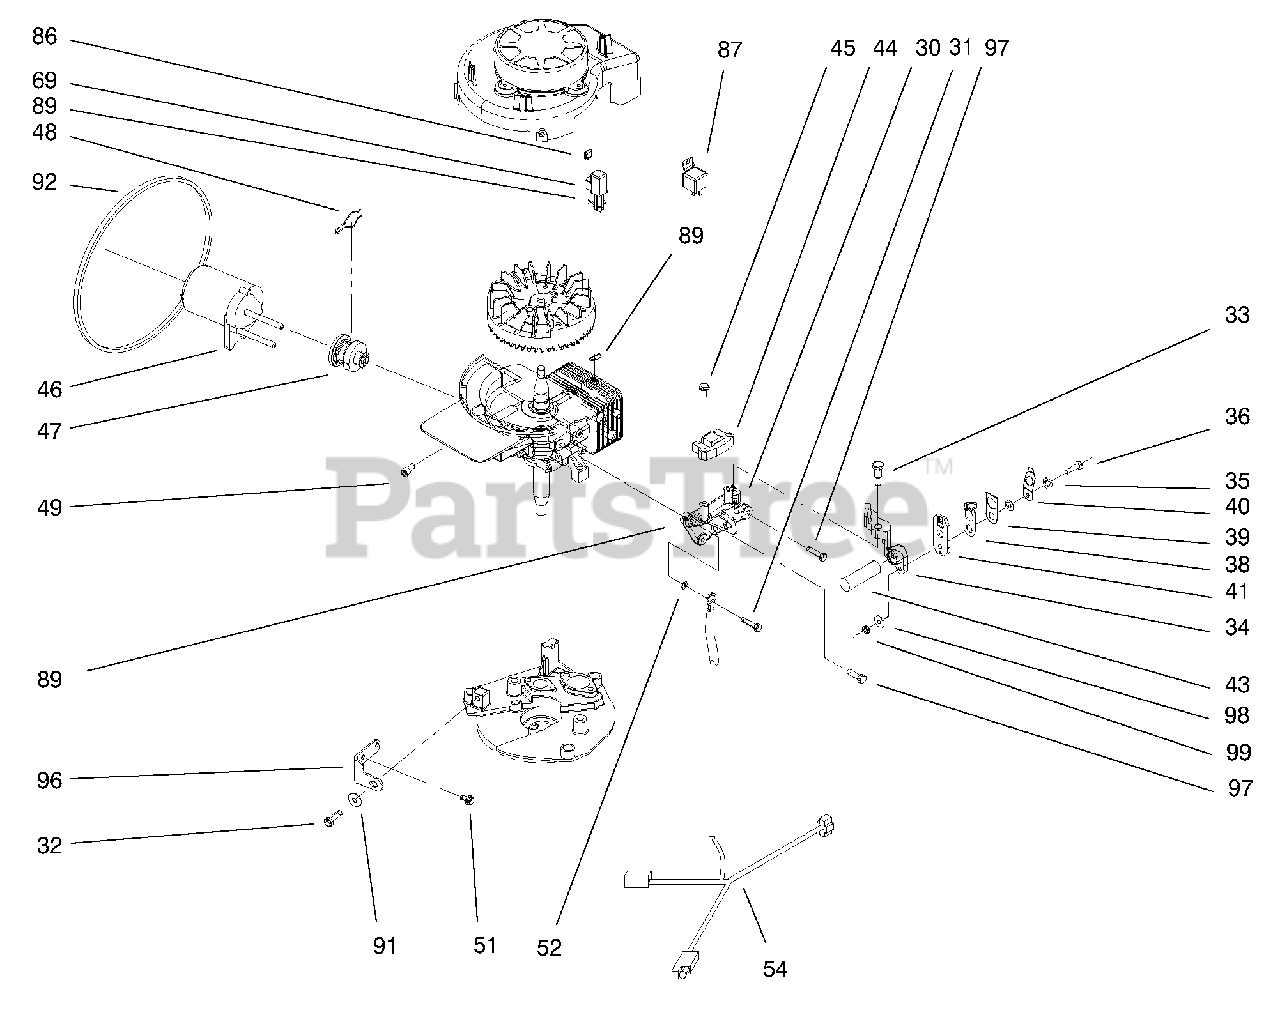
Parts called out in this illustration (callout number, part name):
30	Bracket-Alternator/ Brake
31	Screw-HH
32	Screw-HHF
34	Brake ASM
35	Washer
36	Screw-HH
38	Plate-Contact
40	Spring-Contact
41	Case ASM
42	Lead-Wire
43	Spring-Brake
44	Alternator ASM
46	Starter ASM
47	Pinion ASM
48	Spring-Drag
49	Screw-HSH
51	Screw-HH
52	Washer-Lock
54	Wire Harness
69	Rectifier
86	Mounting Clip
87	Relay, Spdt
89	Strap-Tie
91	Washer-Flat
92	Tie-Cable
97	Screw-HH
98	Washer-Lock/Ext
99	Locknut
